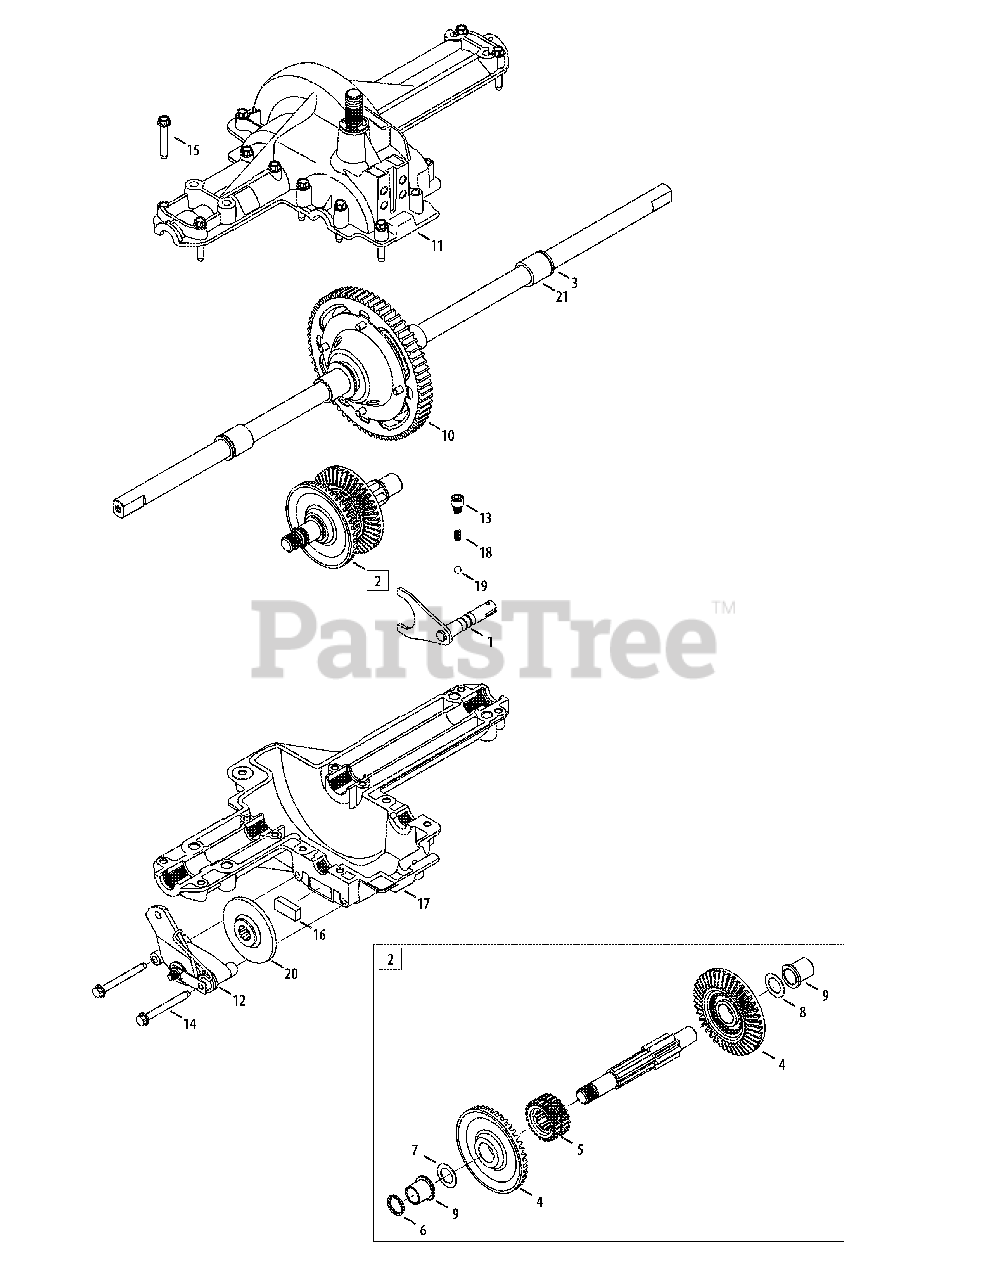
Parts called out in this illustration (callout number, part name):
1	Detent Shaft Ass’y
2	Drive Shaft
3	Oil Seal .750 x 1.00 x .125
4	Bevel Gear, 42 tooth spline
5	Single Speed Clutch Collar
6	Seal .625 x .812 x .094
7	Flat Washer 5/8 ID x 1.0 OD x .030
7	Flat Washer 5/8 ID x 1.0 OD x 0.040
7	Flat Washer 5/8 ID x 1.0 x .020
7	Thrust Wash. 5/8" ID x 1.0" OD x .035
7	Thrust Wash. 5/8" ID x 1.0" OD x .025
8	Flange Bearing 5/8 x 3/4
9	Flange Bearing 5/8 x 15/16
10	Differential Assembly
11	Upper Housing
12	Brake Assembly
13	Self-Tap Scr. 5/16-18 x .375
14	Self-Tap Scr. 1/4-20 x 2.375
15	Self-Tap Scr. 1/4-20 x 1.625
17	Lower Housing
18	Compression Spring
19	Ball Detent .250 Dia.
21	Sleeve Bearing 3/4 ID x 1.0
